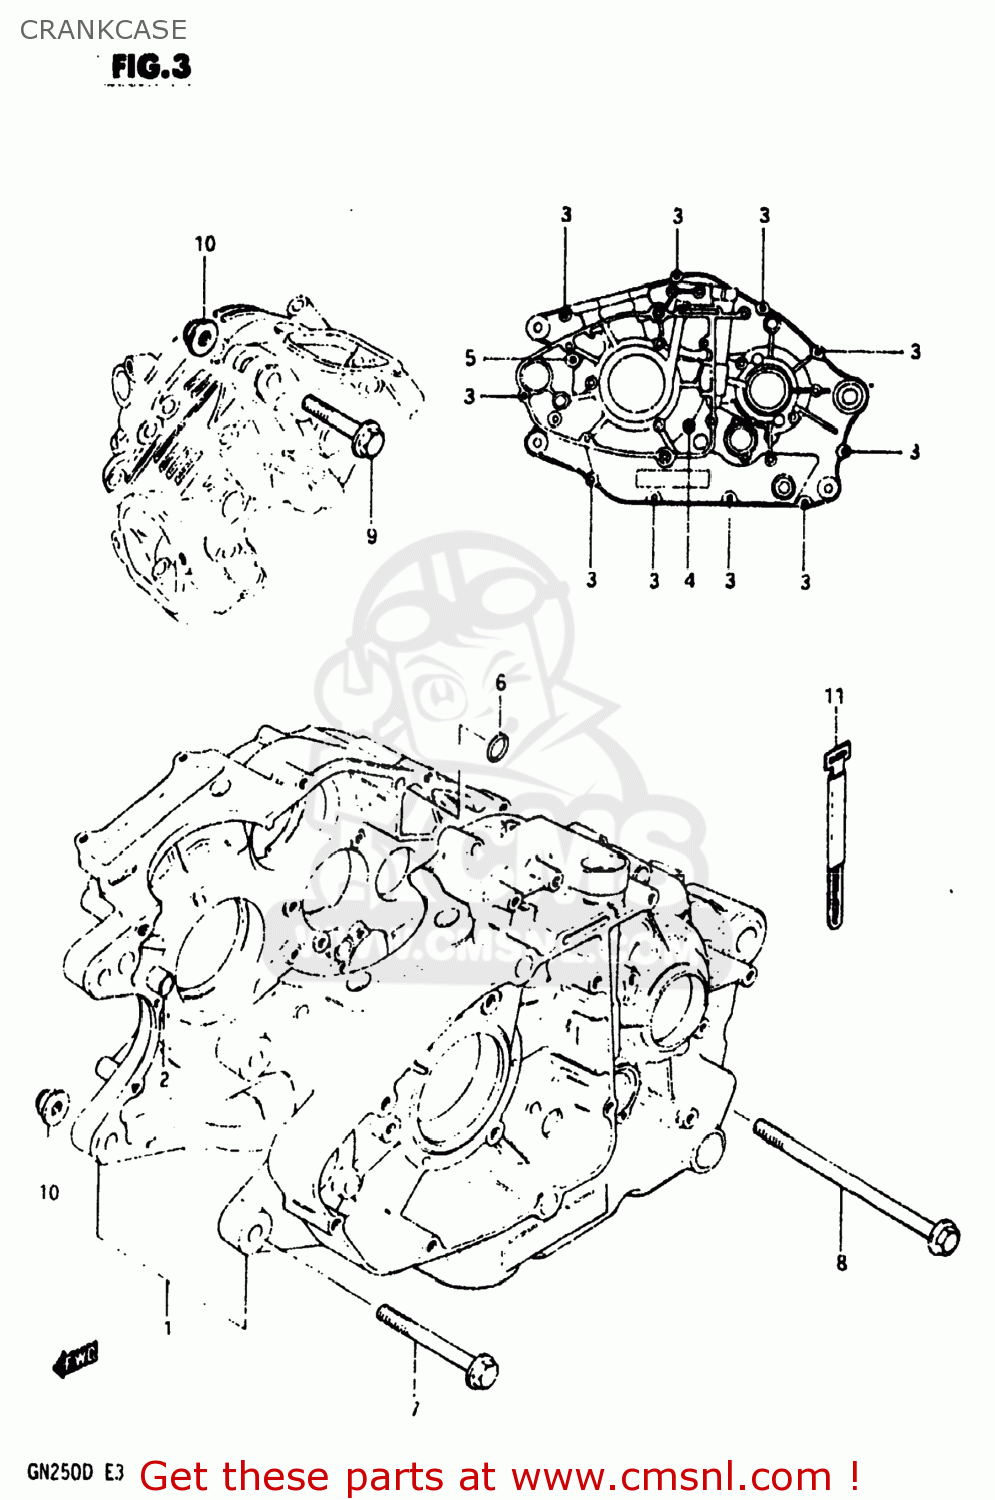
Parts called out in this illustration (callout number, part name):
1	CRANKCASE SET
2	PIN
3	BOLT (6X35)
4	BOLT (6X55)
5	BOLT
6	O-RING
7	BOLT(8X67)
8	BOLT(8X100)
9	BOLT(8X50)
10	NUT
11	CLAMP,AIR CLEANER DRAIN TUBE
